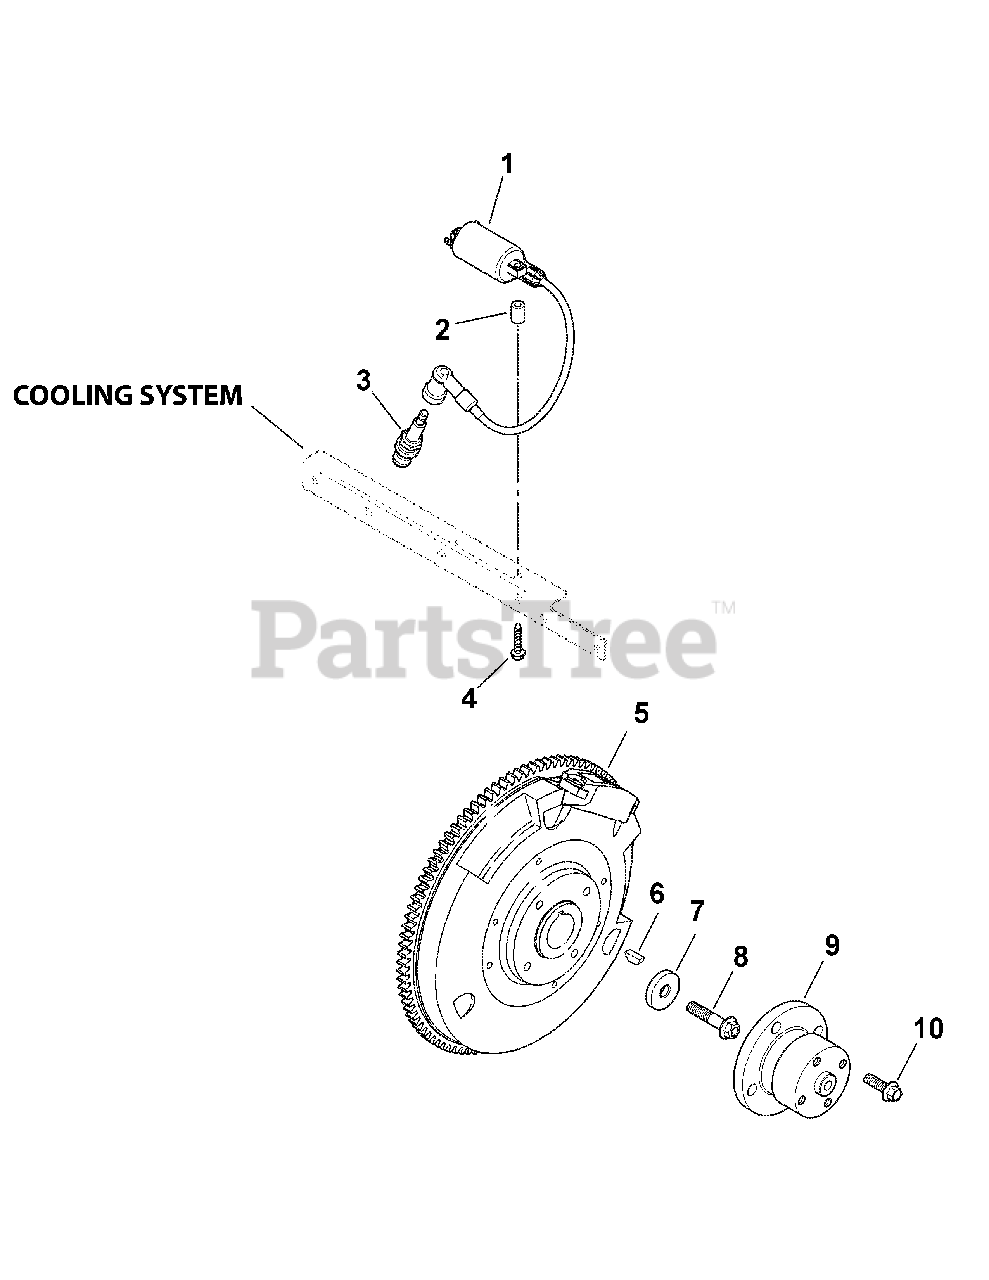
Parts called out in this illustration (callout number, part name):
1	Coil, Ignition
4	Screw, Thrd Frm, M6 x 1.0 x 45
5	Kit, Flywheel
6	Key, 3/16" x 5/8"
7	Washer, Flat, 13/32"
8	Screw, Flg, M10 x 1.5 x 45
9	Shaft, Front Drive
10	Screw, Flg, M8 x 1.25 x 25
